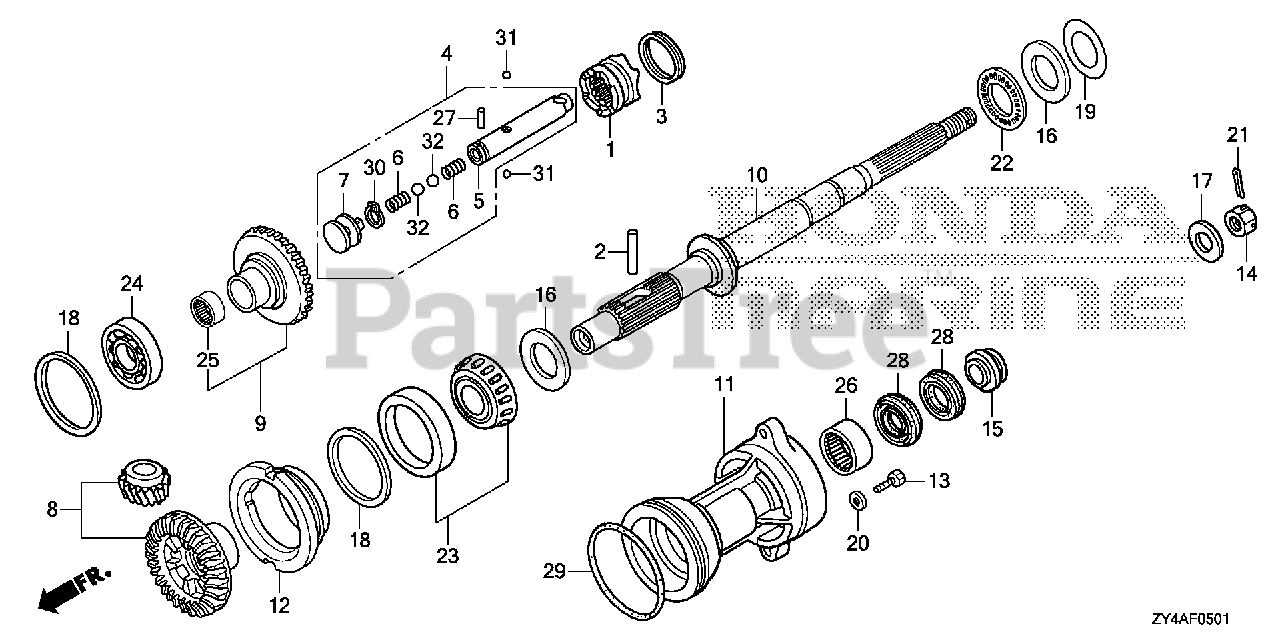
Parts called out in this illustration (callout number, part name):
1	SHIFTER, CLUTCH
2	PIN, SHIFTER (8X50)
3	RING, CROSS PIN
4	SLIDER, SHIFT
5	SLIDER, SHIFT
6	SPRING, SHIFT
7	PLATE, SHIFT
8	GEAR SET (COUNTER ROTATION)
9	GEAR, BEVEL (RVS. 28T) (COUNTER ROTATION)
10	SHAFT, PROPELLER (COUNTER ROTATION)
11	HOLDER, PROPELLER SHAFT *NHB14M* (AQUA MARINE SILVER METALLIC)
12	HOLDER, BEARING (COUNTER ROTATION)
13	BOLT, HEX. (12X45)
14	NUT, CASTLE (18MM)
15	WASHER, PROPELLER THRUST
16	WASHER, THRUST BEARING
17	WASHER, PROPELLER
18	SHIM A, BEVEL (0.10)
18	SHIM B, BEVEL (0.15)
18	SHIM C, BEVEL (0.30)
18	SHIM D, BEVEL (0.50)
19	SHIM A, THRUST (0.10)
19	SHIM B, THRUST (0.15)
19	SHIM C, THRUST (0.30)
19	SHIM D, THRUST (0.50)
20	WASHER, PLAIN (12MM)
21	PIN, SPLIT (4.0)
22	BEARING, THRUST (F)
23	BEARING, TAPER (50X90X21.5)
24	BEARING, ANGULAR (50X90X30.2)
25	BEARING, NEEDLE (28X39X30)
26	BEARING, NEEDLE (32X42X30)
27	ROLLER (3X13.8)
28	SEAL, WATER (30X45X7)
29	O-RING (110X3.1)
30	CIRCLIP (OUTER) (15MM)
31	BALL, STEEL (#7) (7/32)
32	BALL, STEEL (#12) (3/8)
